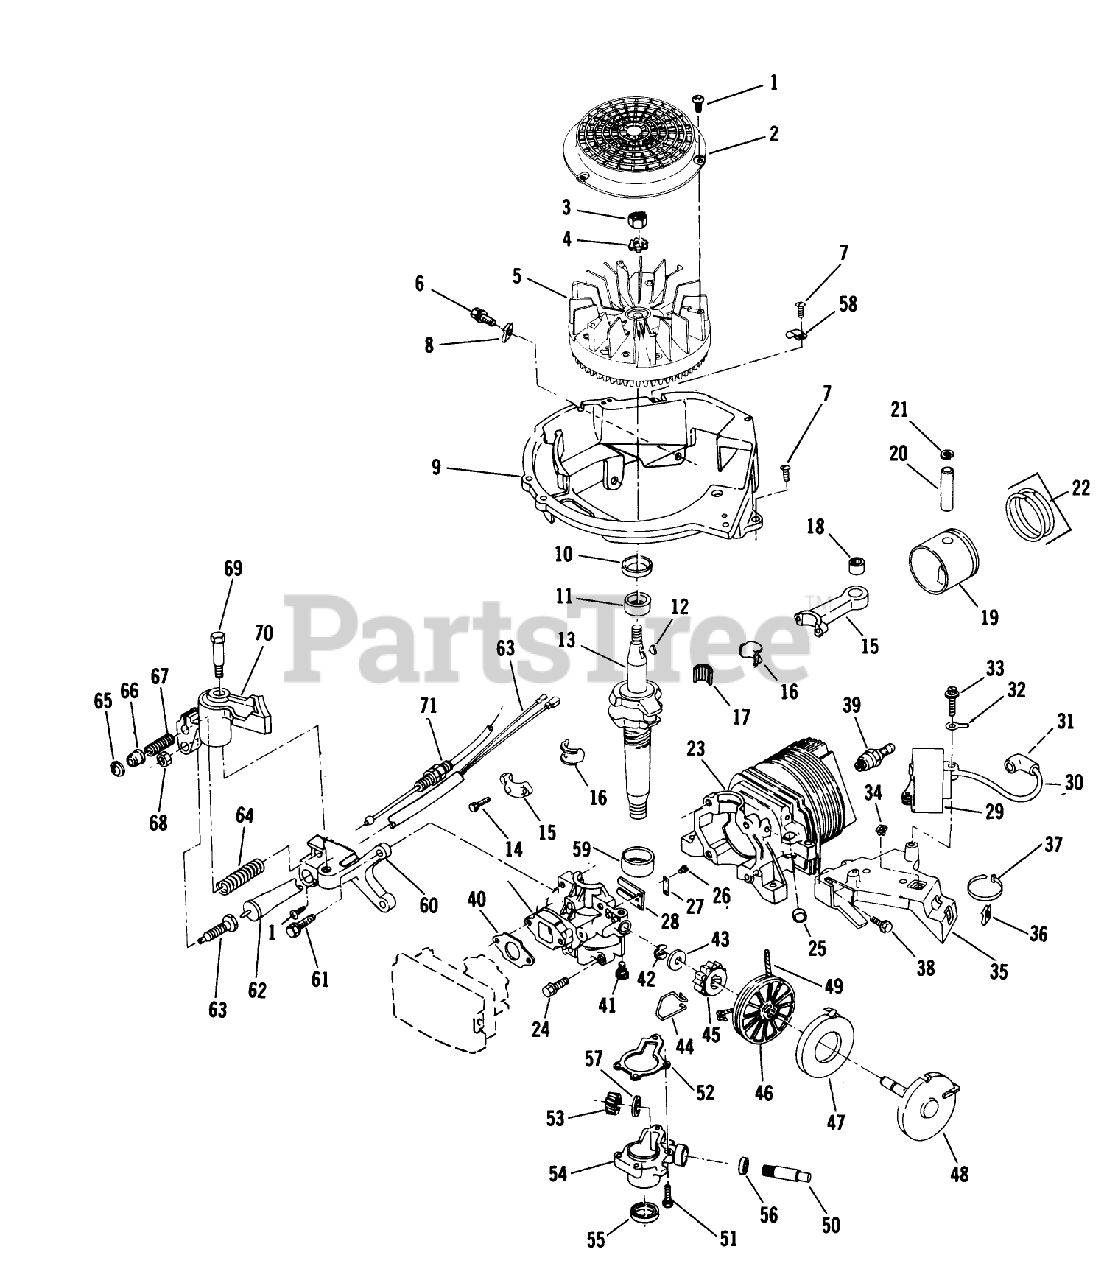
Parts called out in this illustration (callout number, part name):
1	SCREW F
2	SCREEN F'WHEEL S
3	NUT
6	SCREW-SEMS
7	SCREW F
11	BEARING V
12	KEY
15	SCREW-HSH
16	LINER ASM
18	BEARING AY F
22	RING-RETAINING
24	SCREW S
25	PLUG-CORE VF
27	PLATE-BACKUP, REED
30	HT LEAD&COVER XEV
32	TERMINAL S
34	NUT-CLIP
36	NUT - SPEED S
40	GASKET CARB S
43	WASHER S
44	SPRING F
46	PULLEY STARTER S
49	ROPE-STARTER
52	GASKET S
53	GEAR, DR SHAFT S
55	SEAL-OIL
56	SEAL S
57	THRUST WASHER
59	BEARING S
60	BRACKET-BRAKE F
63	PLUNGER S
64	SPRING-BRAKE
65	RETAINER S
66	ACTUATOR-LEVER, BRAKE
67	SPRING
71	CONTROL CABLE
